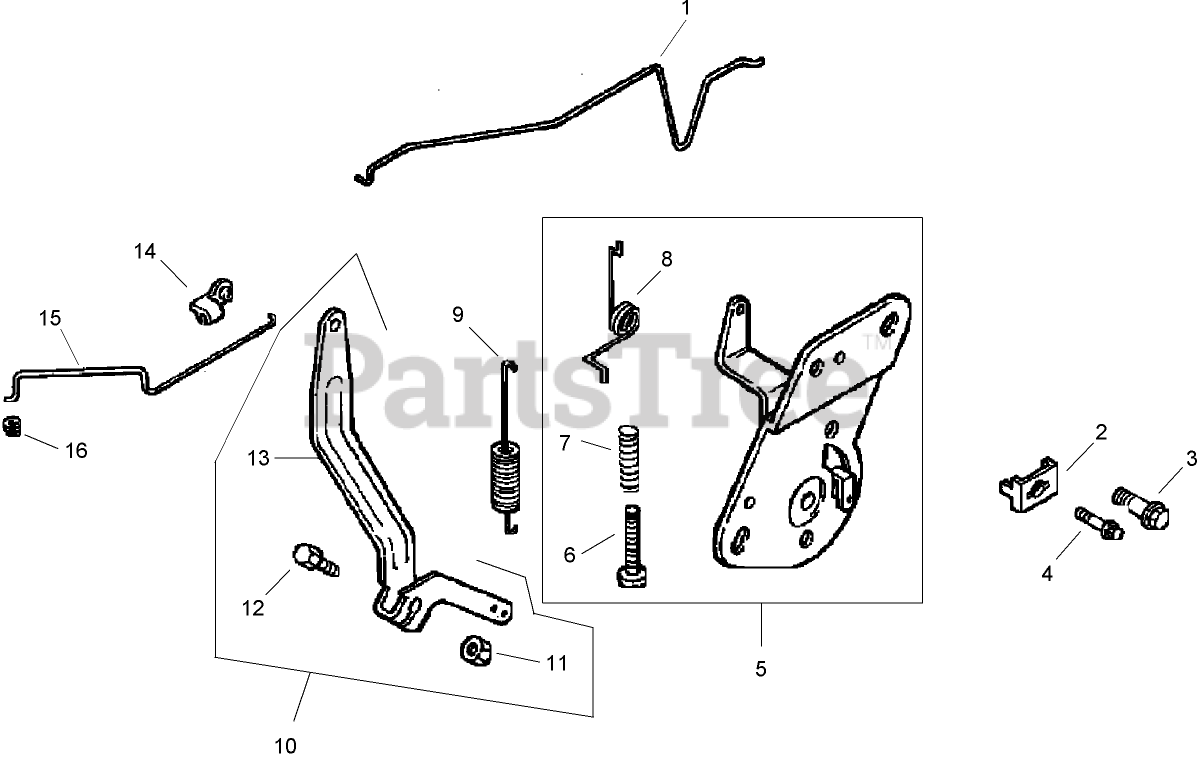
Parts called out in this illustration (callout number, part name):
1	Linkage-Choke
2	CLAMP-CABLE
3	SCREW-FLANGE, THREAD FORMING (M5X0.8X16)
4	Screw-Socket, 6 Lobed (Thread Forming, M6x1.0x20)
5	Control, speed assembly (Includes 6-8)
6	Screw-Pan Head (w/loctite)
7	Spring-Control, Speed
8	Spring-Return, Choke
9	Spring-Governor
10	Kit, Governor Lever (Incl 10-12)
11	Nut-Flange, Hex (1/4-20)
12	Bolt-Square Neck, Round Head (1/4-20x1)
13	Lever-Governor
14	BUSHING-RETAINING, LINKAGE
15	Linkage-Throttle
16	BUSHING-LINKAGE, THROTTLE
